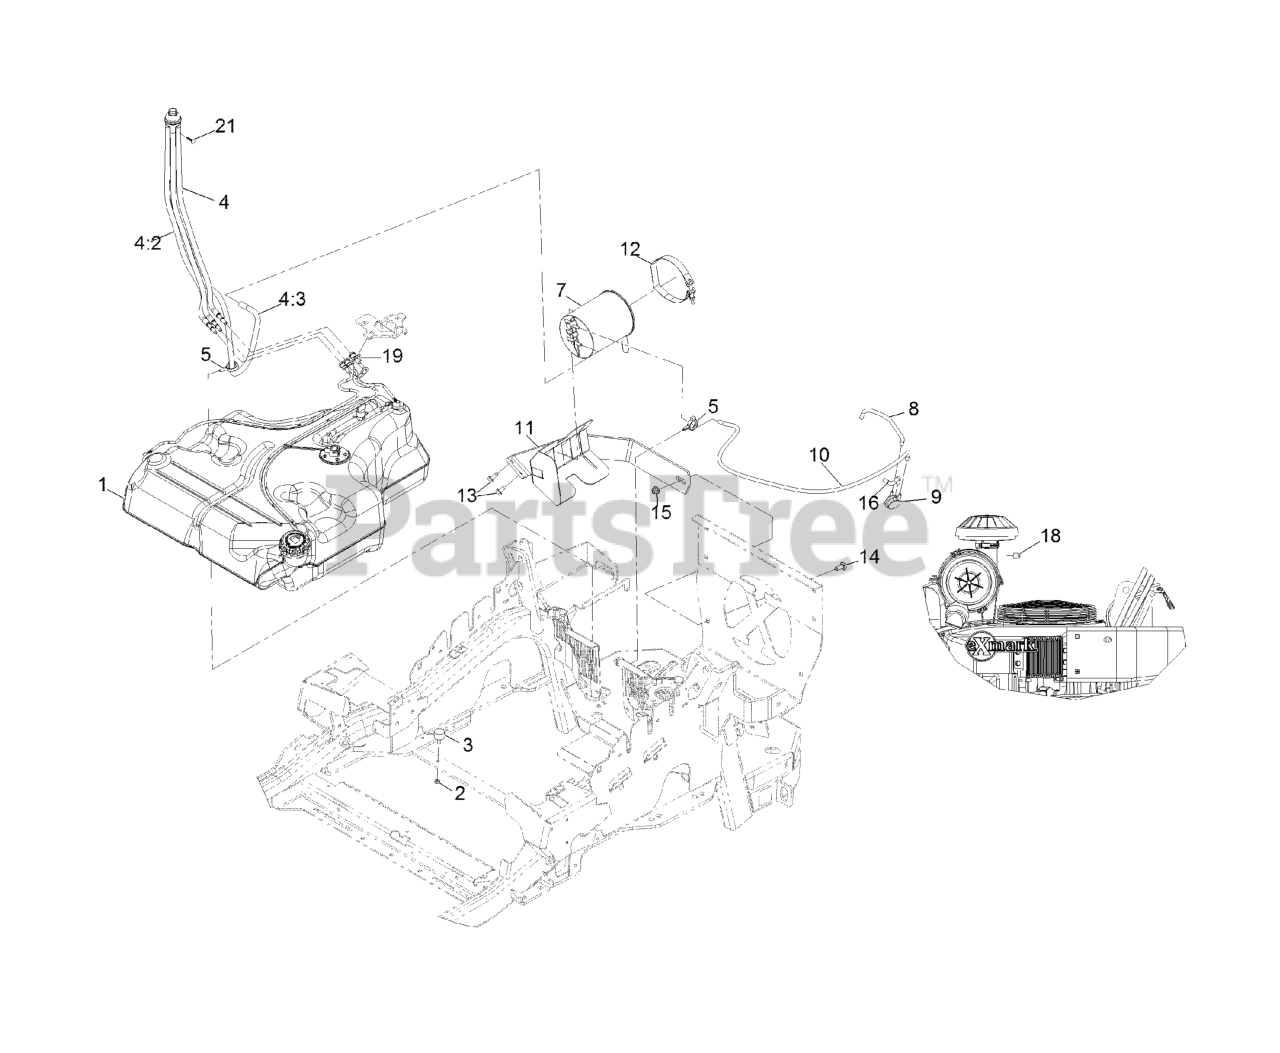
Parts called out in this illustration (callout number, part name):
1	ASM-8 GALLON FUEL TANK
2	NUT-JAM
4	FUEL MANIFOLD VENT ASM
4:2	HOSE-FUEL
4:3	HOSE-FUEL
5	CLAMP-HOSE
7	CANISTER-CARBON, 1200CC
8	HOSE-VENT,FORMED
9	VALVE-CONTROL, VACUUM
10	HOSE,VENT,FORMED
11	MOUNT-CANISTER
12	CLAMP, T-BOLT
13	Screw-HWH 5/16-18 X 3/4 Tf
14	SCREW-CARR
15	NUT-HF, NI
16	HOSE-VENT, FORMED
18	PLUG-PORT
19	RETAINER-LINE, VAPOR
21	PLUG-PLASTIC
